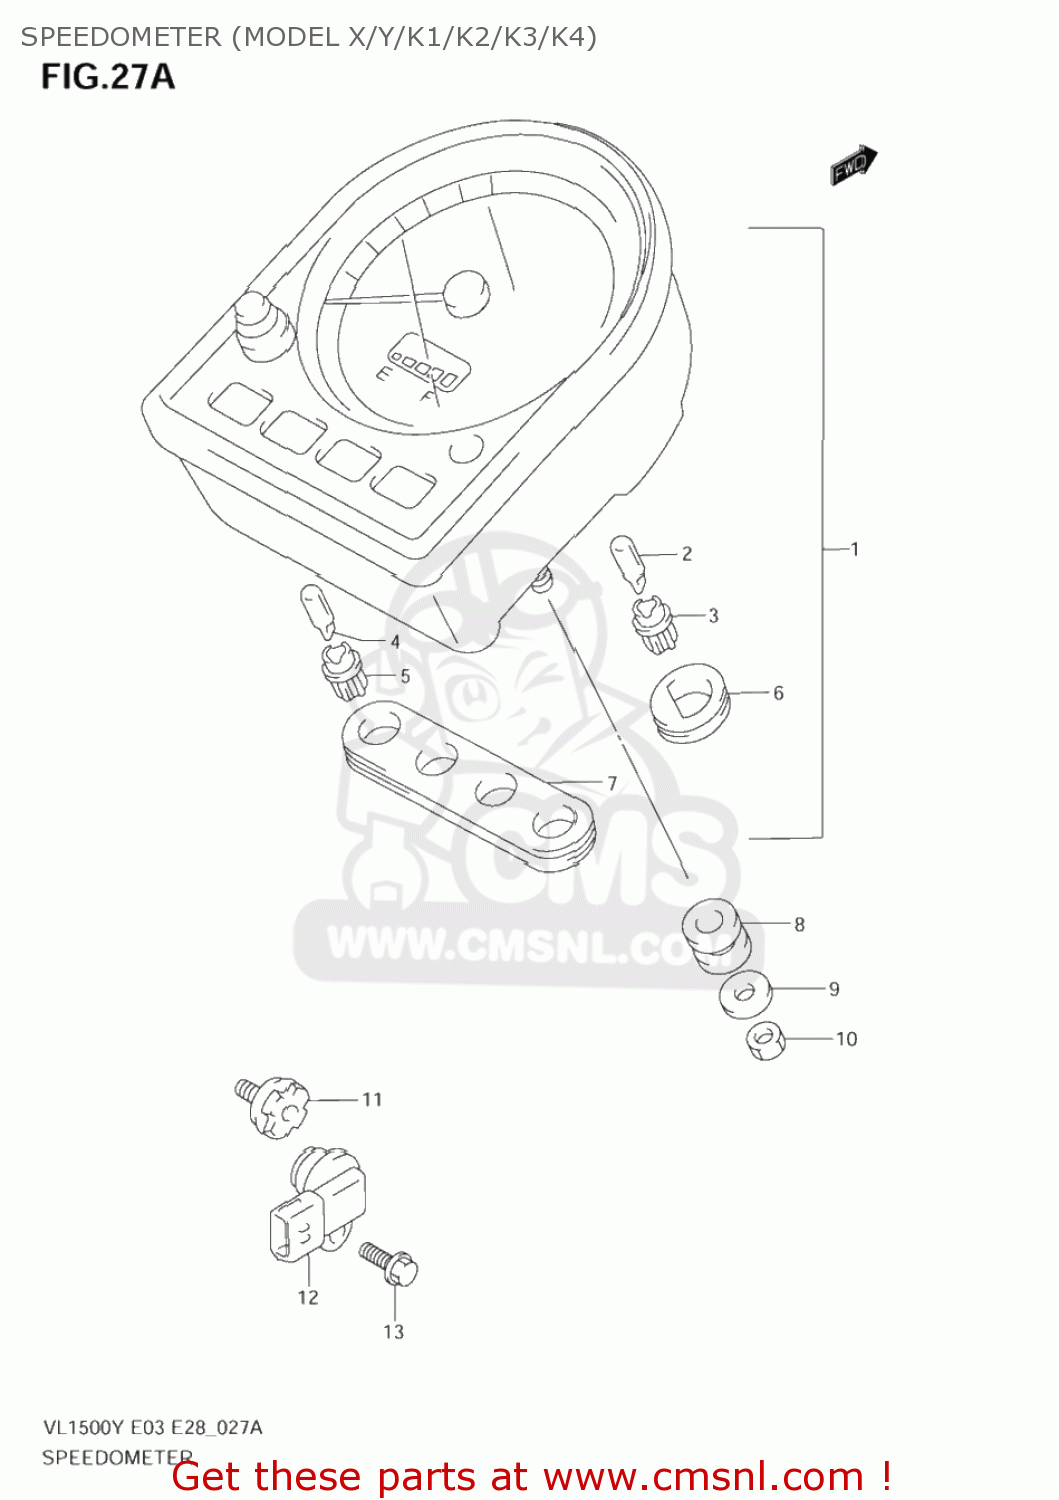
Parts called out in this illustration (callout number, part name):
1	SPEEDOMETER ASSY
2	BULB(14V,0.84W)
3	SOCKET,BULB
4	BULB(12V1.7W,WB372,T7)
5	SOCKET
6	BLIND,CAP
7	BLIND,CAP
8	CUSHION,METER
9	WASHER(5.5X16X1.2)
10	NUT
11	ROTOR,SPEED
12	SENSOR,SPEED
13	BOLT(6X16)
